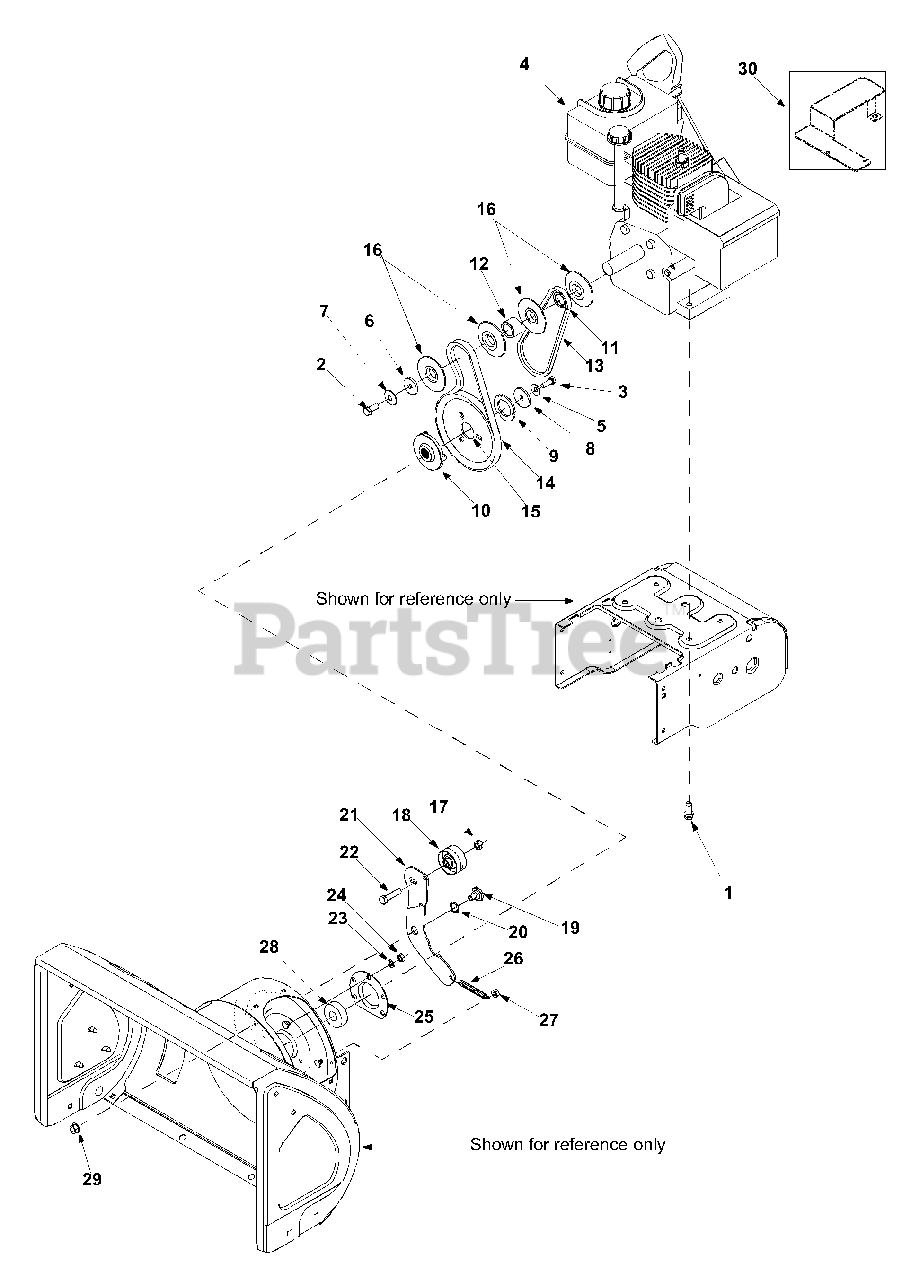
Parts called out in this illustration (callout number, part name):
1	TT Sems Scr. 3/8-16 x 1.0"
2	Hex Bolt 3/8-24 x 0.875"
3	Lock Bolt 5/16-24 x 0.875"
4	Engine
5	Bell Washer
6	Flat Washer
7	Bell Washer
8	Flat Washer
9	Special Washer
10	Pulley: Adapter
11	Spacer
12	Spacer
13	V-Belt
14	V-Belt
15	Auger Pulley
16	Pulley Half
17	Hex Lock Nut 3/8-16
18	Flat Idler
19	Shoulder Screw 3/8-16
20	Wave Washer
21	Auger Idler Bracket
22	Hex Bolt 3/8-16 x 1.50"
23	Lock Washer 5/16
24	Hex Nut 5/16-18
25	Bearing Housing
26	Extension Spring
27	Patch Nut
28	Ball Bearing
29	Flange Lock Nut
30	Heat Shield: Muffler Guard
